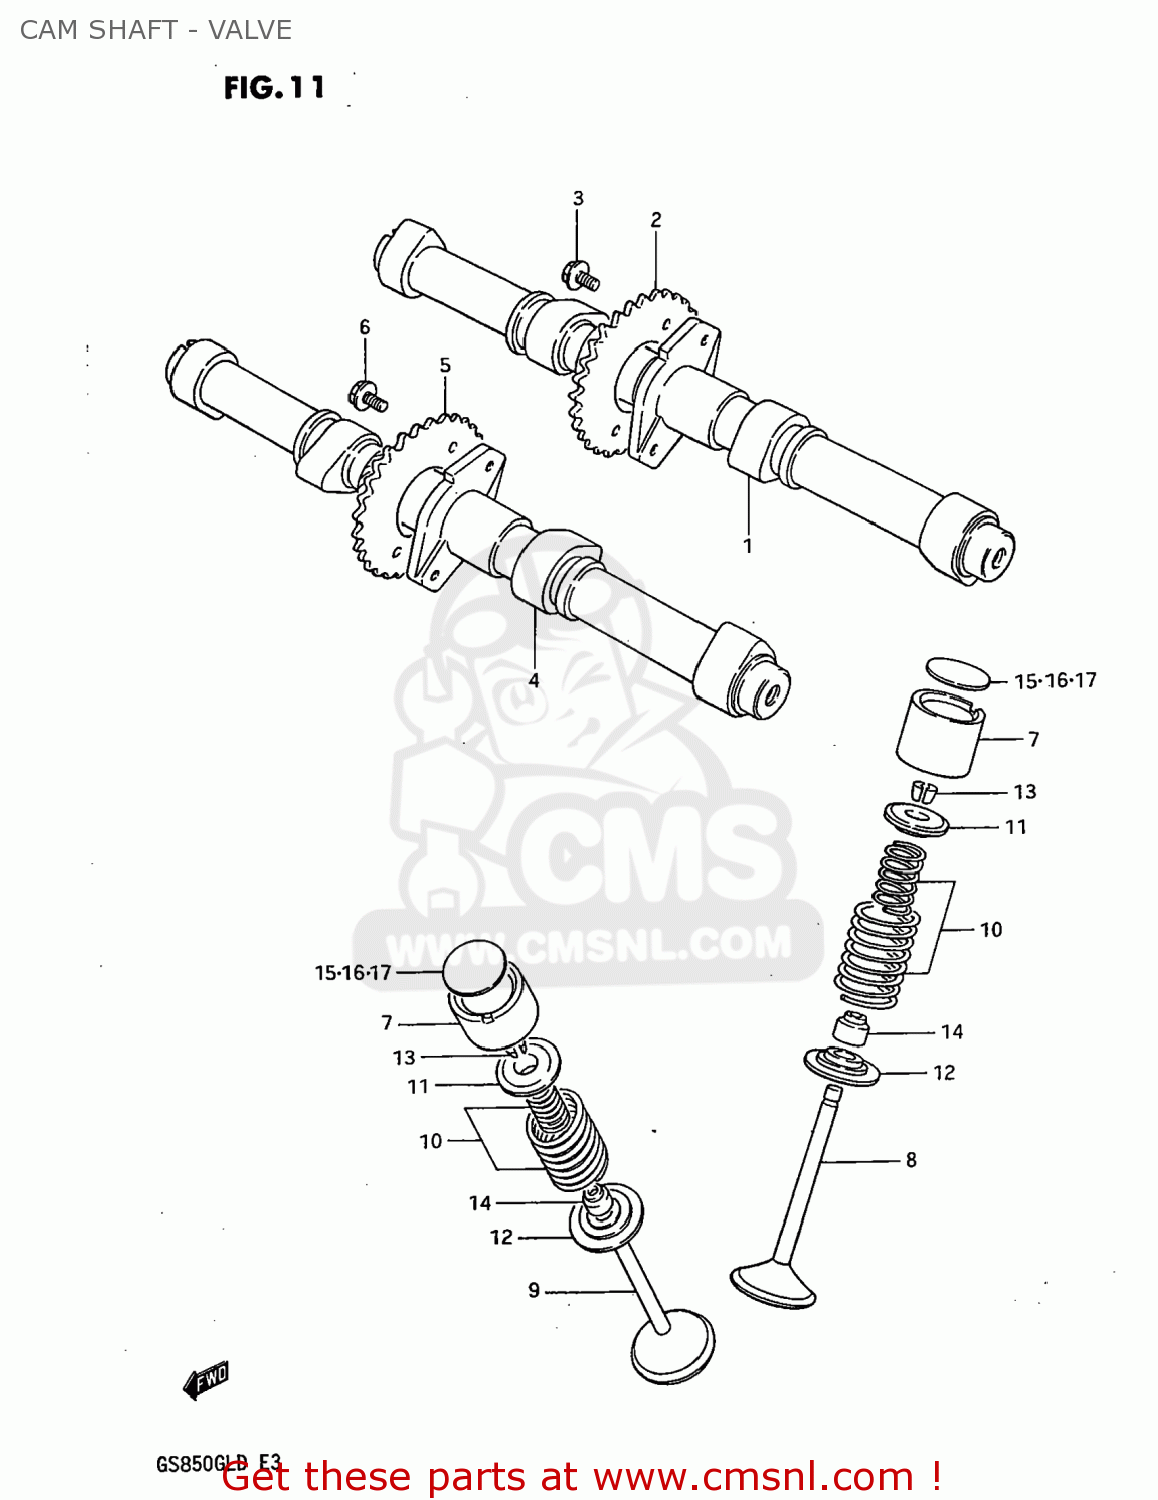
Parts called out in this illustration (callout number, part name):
1	CAMSHAFT,INTAKE
2	SPROCKET,INTAKE CAMSHAFT
3	BOLT(7X11)
4	CAMSHAFT,EXHAUST
5	SPROCKET,EXHAUST CAMSHAFT
6	BOLT(7X11)
7	TAPPET
8	VALVE,INTAKE
9	VALVE,EXHAUST
10	SPRING SET,VALVE
11	RETAINER,VALVE SPRING
12	SEAT,VALVE SPRING
13	COTTER VALVE
14	SEAL,OIL(7X14.4X9)
15	SHIM,TAPPET
16	SHIM,TAPPET
17	SHIM,TAPPET
18	SHIM SET,TAPPET
19	CASE
